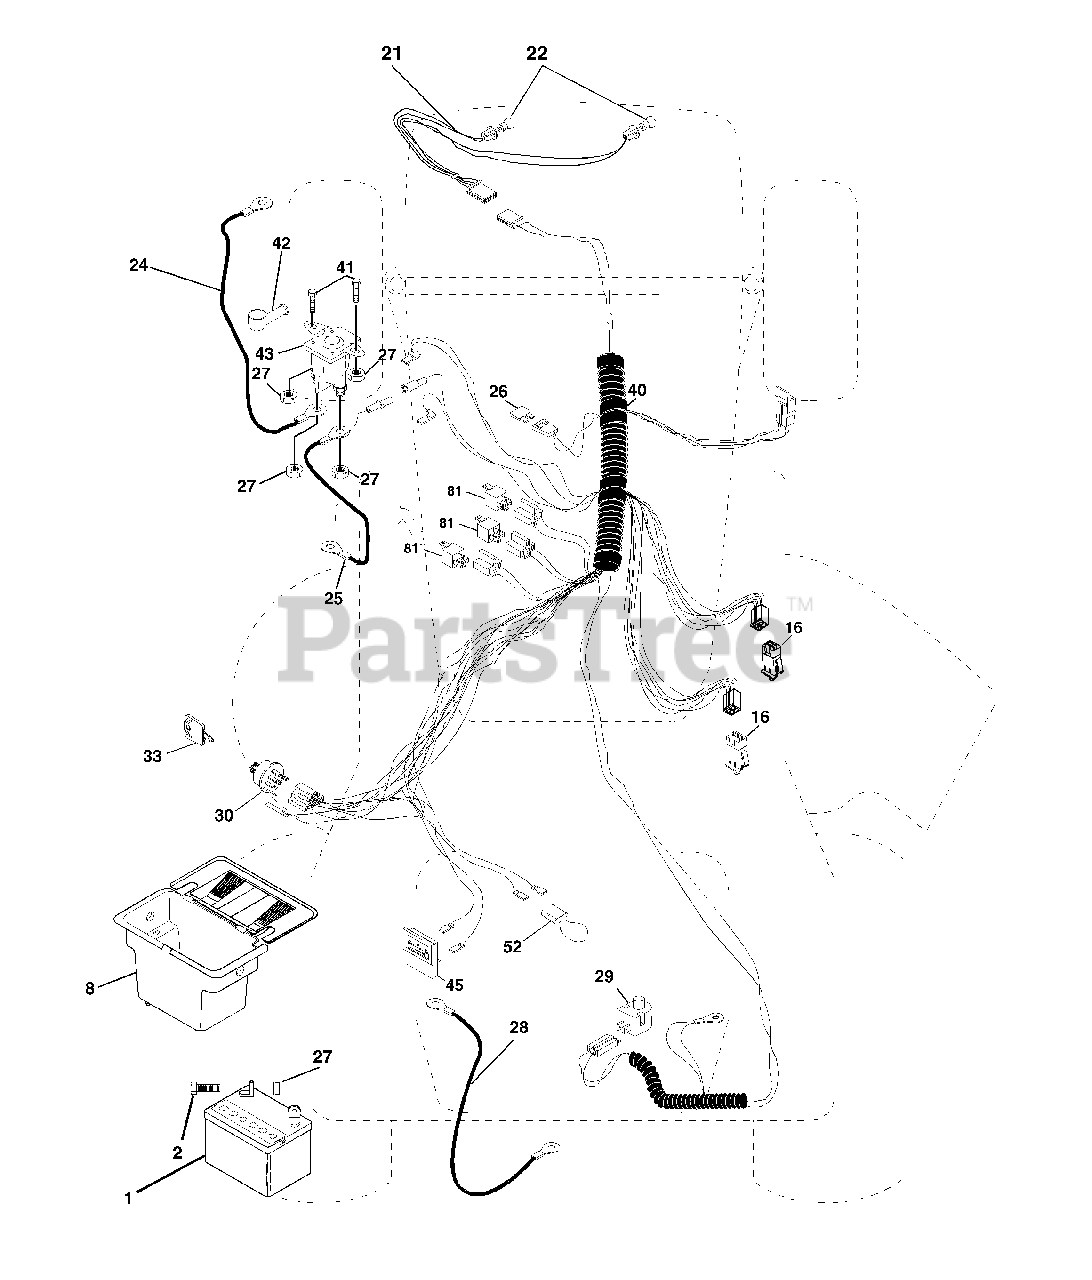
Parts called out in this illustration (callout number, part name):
1	Battery 12 Volt 25 Amp
2	Bolt Hex Hd 1/4-20unc X 3/4
8	Case Battery
16	Switch Interlock Push -In
21	Harness Asm Light W/4152J
22	Bulb Light #1156
24	Cable Battery 6 Ga 16"red
25	Cable Battery 6 Ga w/16 wire,red
26	Fuse
27	Nut Keps Hex 1/4-20 unc
28	Cable Ground 6 Ga 12" black
29	Switch Plunger Nc Gray
30	Switch Ign
33	Key Ign
40	Harness Ign
41	Bolt Blk Fin Hex 1/4-20 X 1/2
42	Cover Terminal Red
43	Solenoid
45	Ammeter
52	Protection Wire Loop
81	Relay Asm
